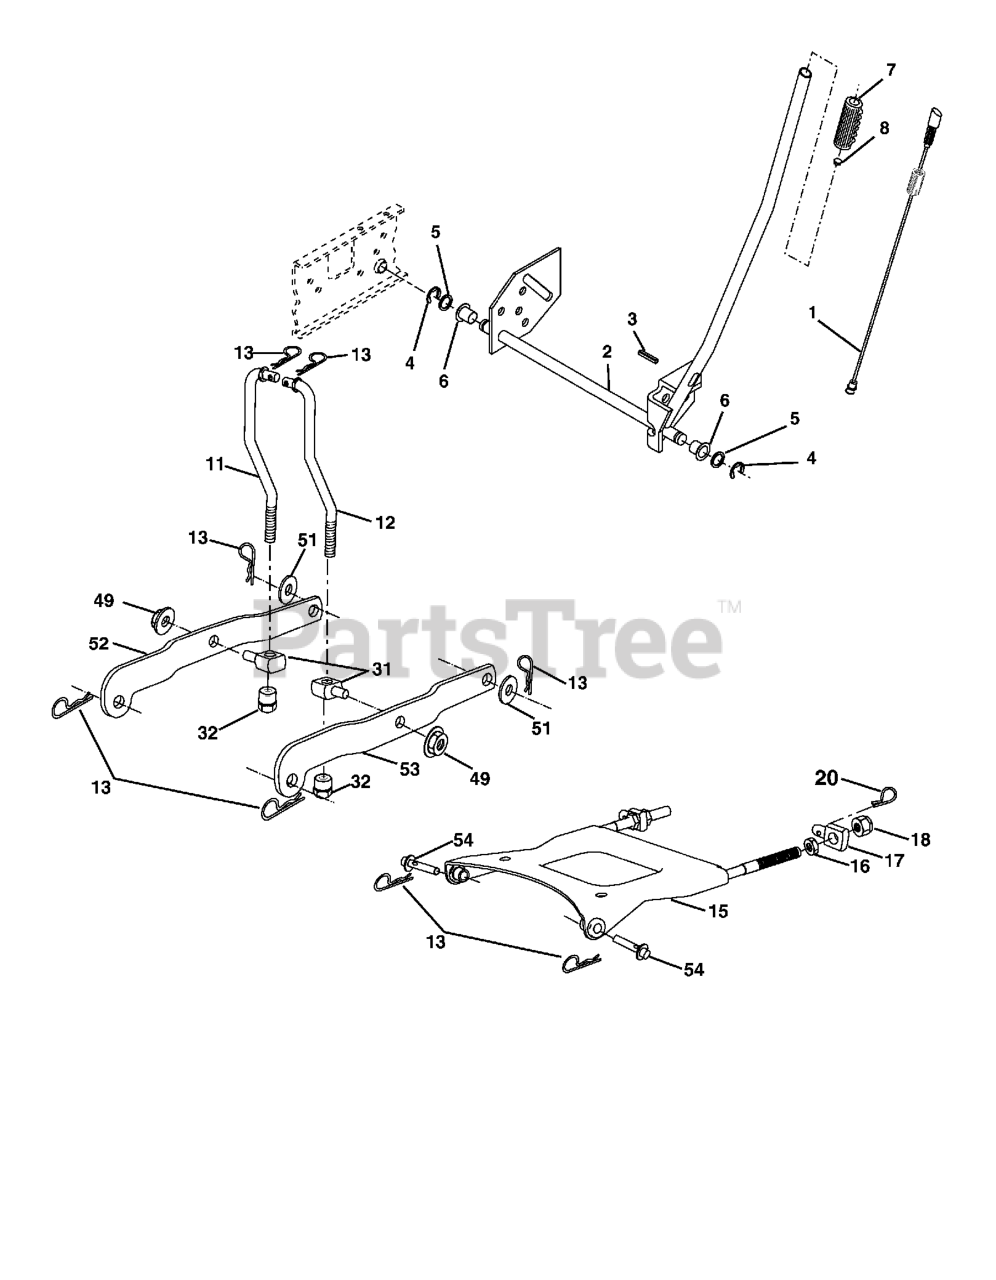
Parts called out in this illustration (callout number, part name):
1	WIRE ASM INNER W/ PLUNGER LT
2	SHAFT ASM R HANDLE
3	PIN GROOVE.
4	RETAINING RING LT
5	WASHER
6	BEARING.NYLON
7	GRIP HANDLE
8	PLUNGER BUT KIT
11	LIFT LINK LH
12	LIFT LINK RH
13	RETAINER-SPRNG RB
15	PLATE ASM SUSP FRONT
16	NUT.HEX.JAM.1/2-13
17	TRUNNION
18	NUT.LK.W/WSH.1/2.
20	SPRING RETAINER
31	TRUNNION
32	NUT, LIFT LINK 7/16-20
49	NUT
51	Washer 1 17/32 X 7/8 X 16 Ga
52	ARM SUSP. REAR LH
53	ARM SUSP REAR RH
54	PIN.FLANGE
